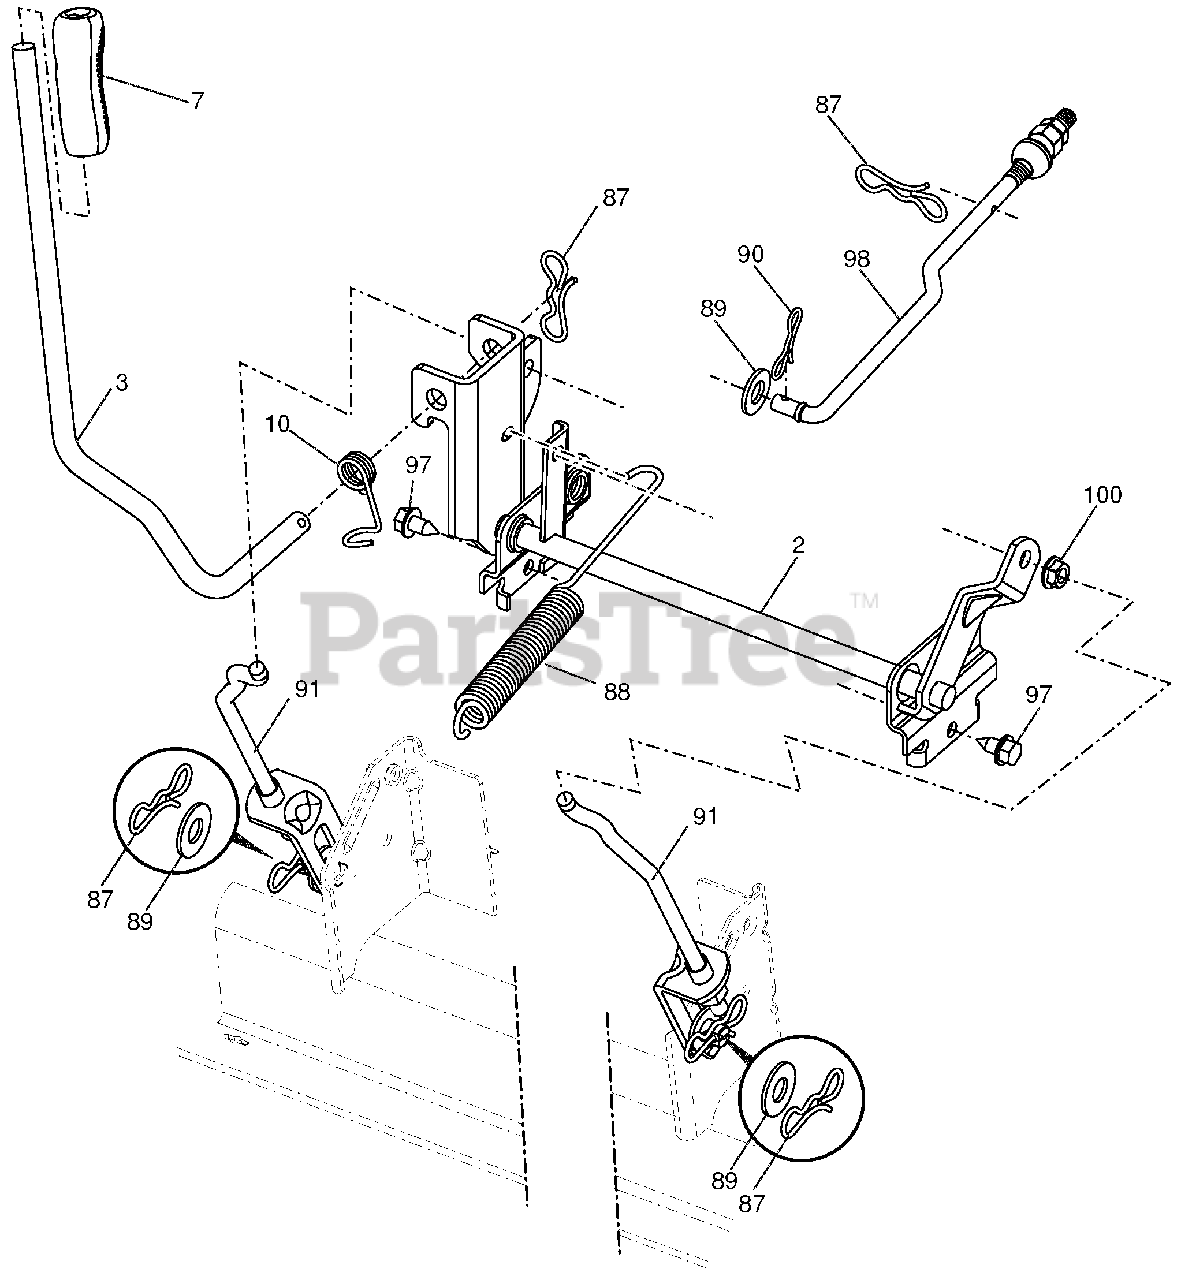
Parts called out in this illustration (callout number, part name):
2	SHAFT ASM.LIFT.CROSS.HD.
3	LEVER.LIFT.HANDLE.LT
7	GRIP.LEVER..5625 ID.BLACK 428
10	SPRING.TORSION.HANDLE.LIFT
87	PIN.COTTER.7/16.BOW TIE LOCK
88	SPRING.LIFT ASSIST
89	WASHER.17/32 X 1-3/16 X 12 GA.
90	PIN.COTTER.5/16.BOW TIE LOCK
91	LINK ASM.LIFT.LH.REAR
97	SCREW.HEXWSH THDR3/8-16X3/4.BL
98	LINK ASM.SUSP.FRONT.MWR.11
100	NUT.CENTERLOCK.3/8-16 UNC.
